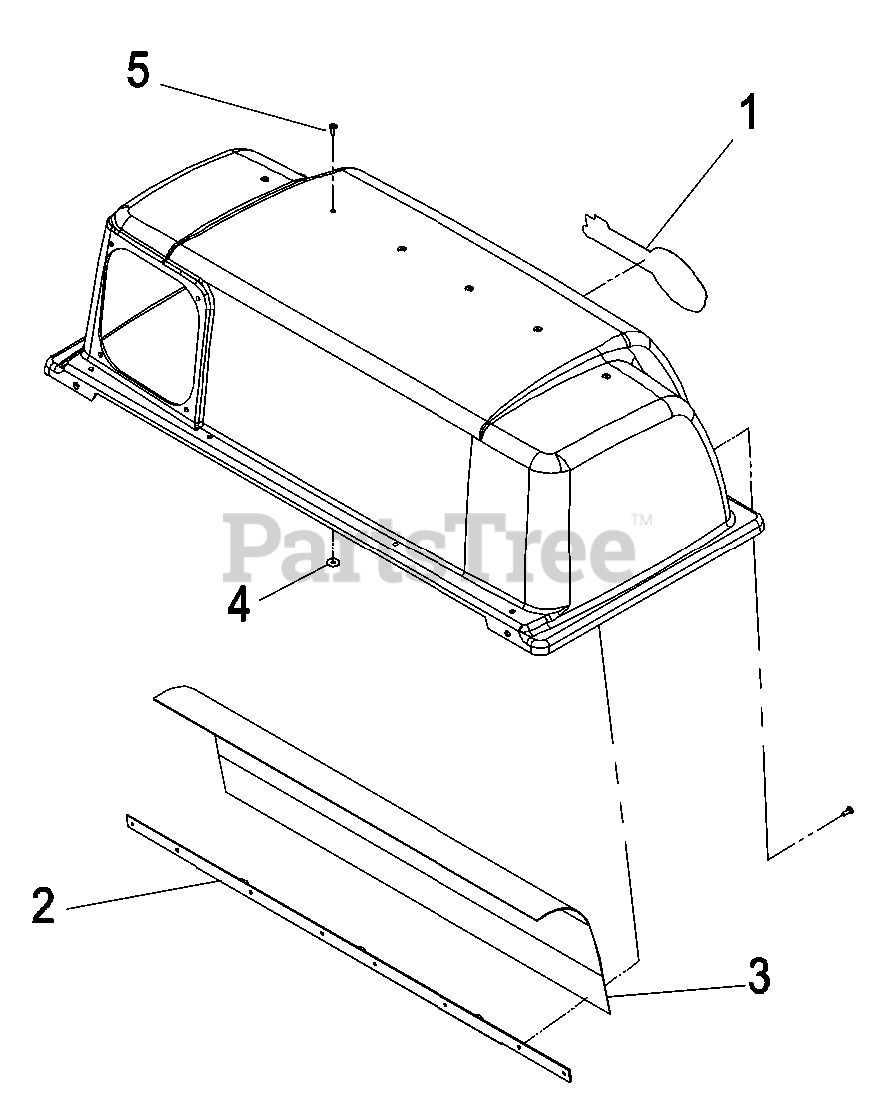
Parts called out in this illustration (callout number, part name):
1	DECAL, EXMARK LOGO
2	SUPPORT-SCREEN
3	SCREEN-BAGGER
4	WASHER-FLAT
5	RIVET-BLIND
